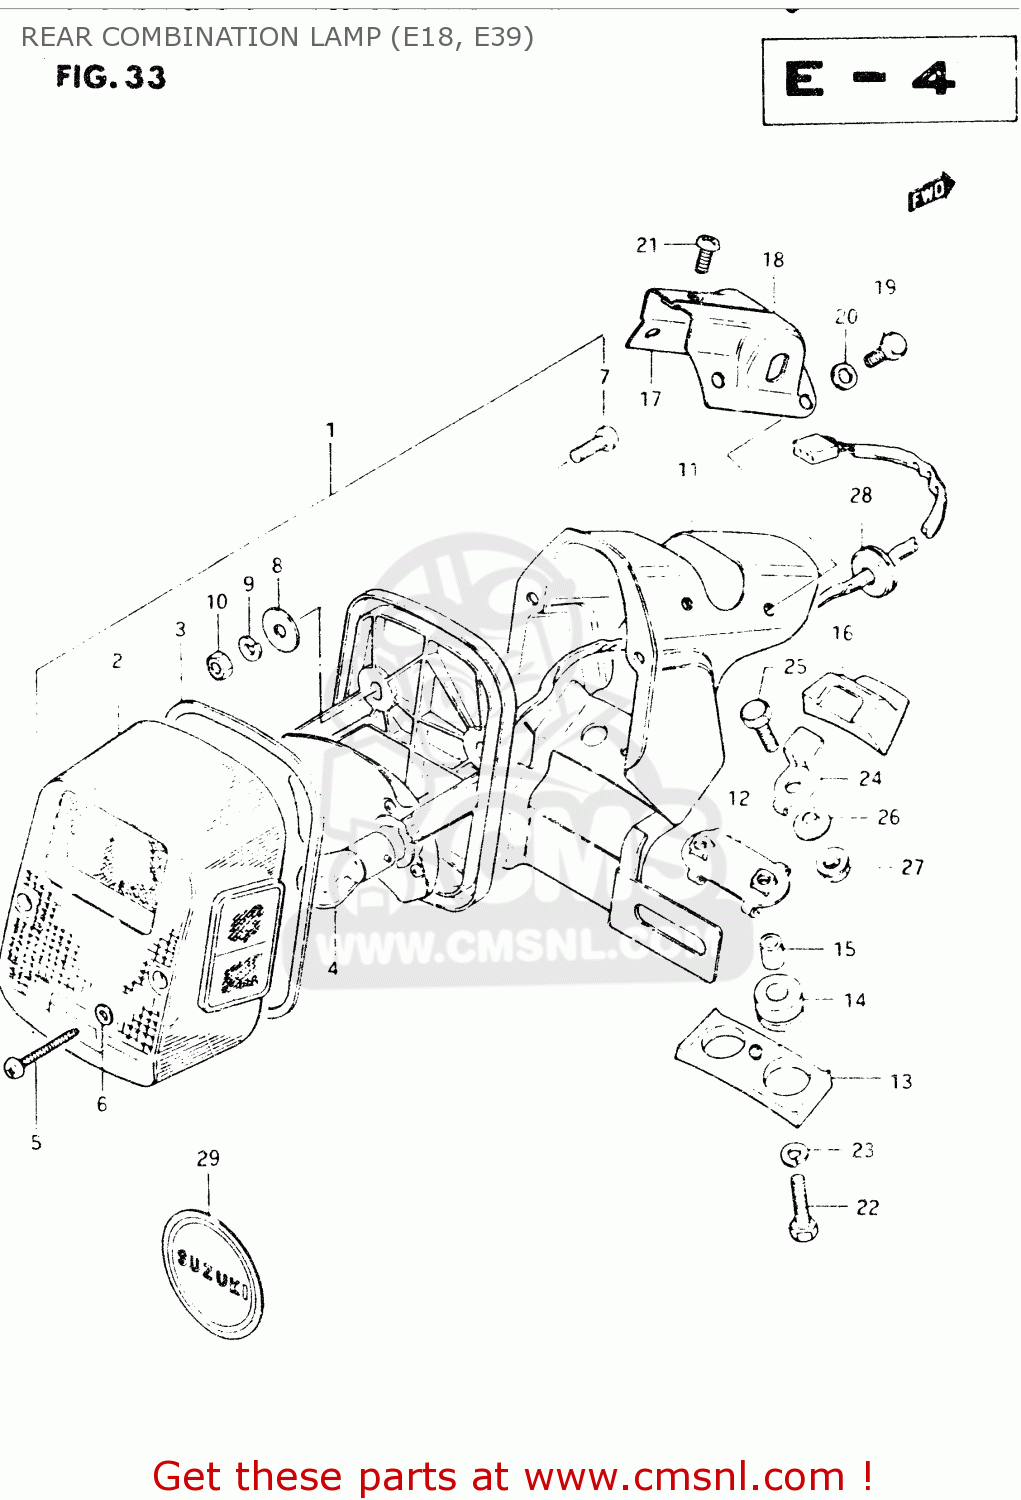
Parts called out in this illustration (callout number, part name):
1	LAMP UNIT, REAR COMBINATION
2	LENS,RR COMBI
3	GASKET (NAS)
4	BULB 12V21/5W
5	SCREW TAPP.
6	GASKET (NAS)
7	SCREW
8	WASHER,REAR COMBINATION LAMP
9	LOCK WASHER
10	NUT
11	BRACKET UNIT
12	PLATE
13	CUSHION
14	CUSHION
15	SPACER
16	CUSHION,REAR COMBINATION LAMP
17	PLATE, RH
18	PLATE, LH
19	BOLT
20	WASHER
21	SCREW
22	BOLT
23	LOCK WASHER
24	PLATE,RR COMBINATION LAMP
25	BOLT, UPPER
26	WASHER,LOCK
27	NUT
28	GROMMET
29	EMBLEM, REAR
